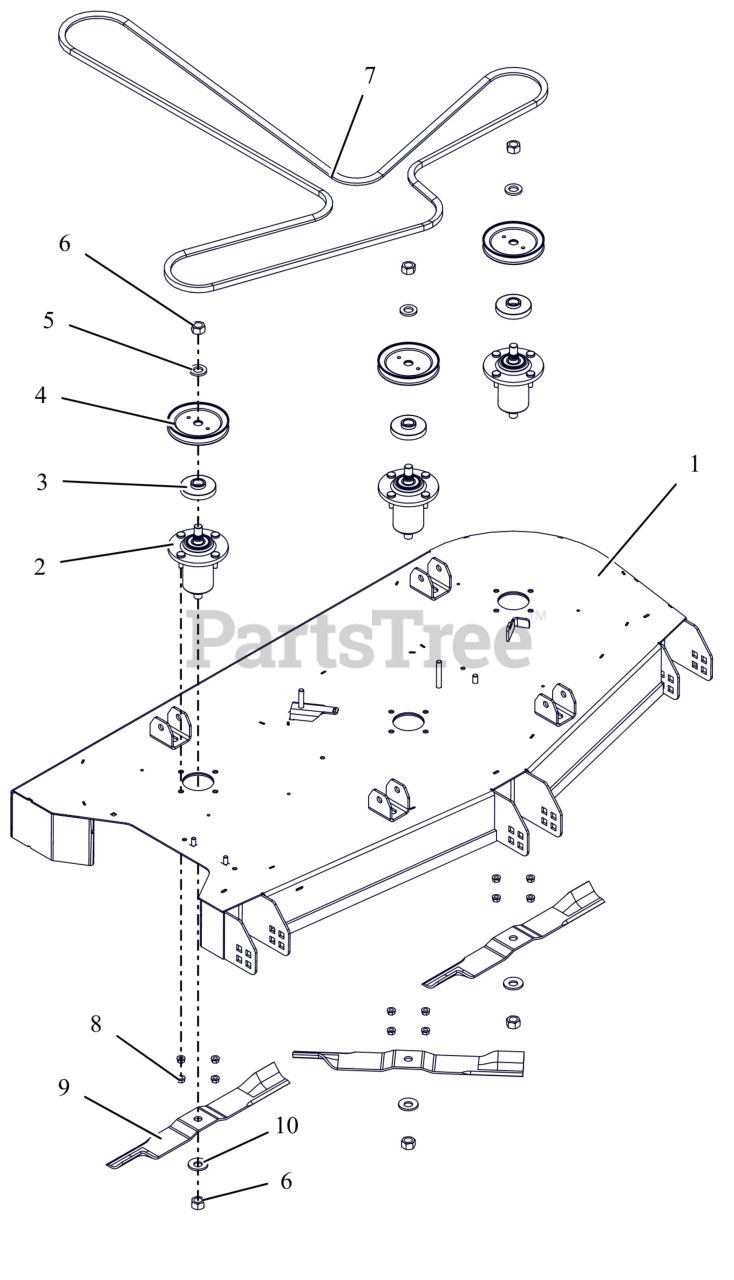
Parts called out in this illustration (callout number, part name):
1	KIT,ARIENS DECK 52" WITH DECALS
2	ASM, ALUMINUM SPINDLE SUB
3	SHIELD, DUST
4	PULLEY, V-4.75 ODX.625 SPLINE ID
6	NUT-STD .625-18 ZCC
7	V-BELT, HA SECTION
8	NUT,LK-CTR-FLG .31-18 GF ZCC
9	BLADE, MOWER 18.0"
10	WSHR-BLVL .669X1.535X.138
